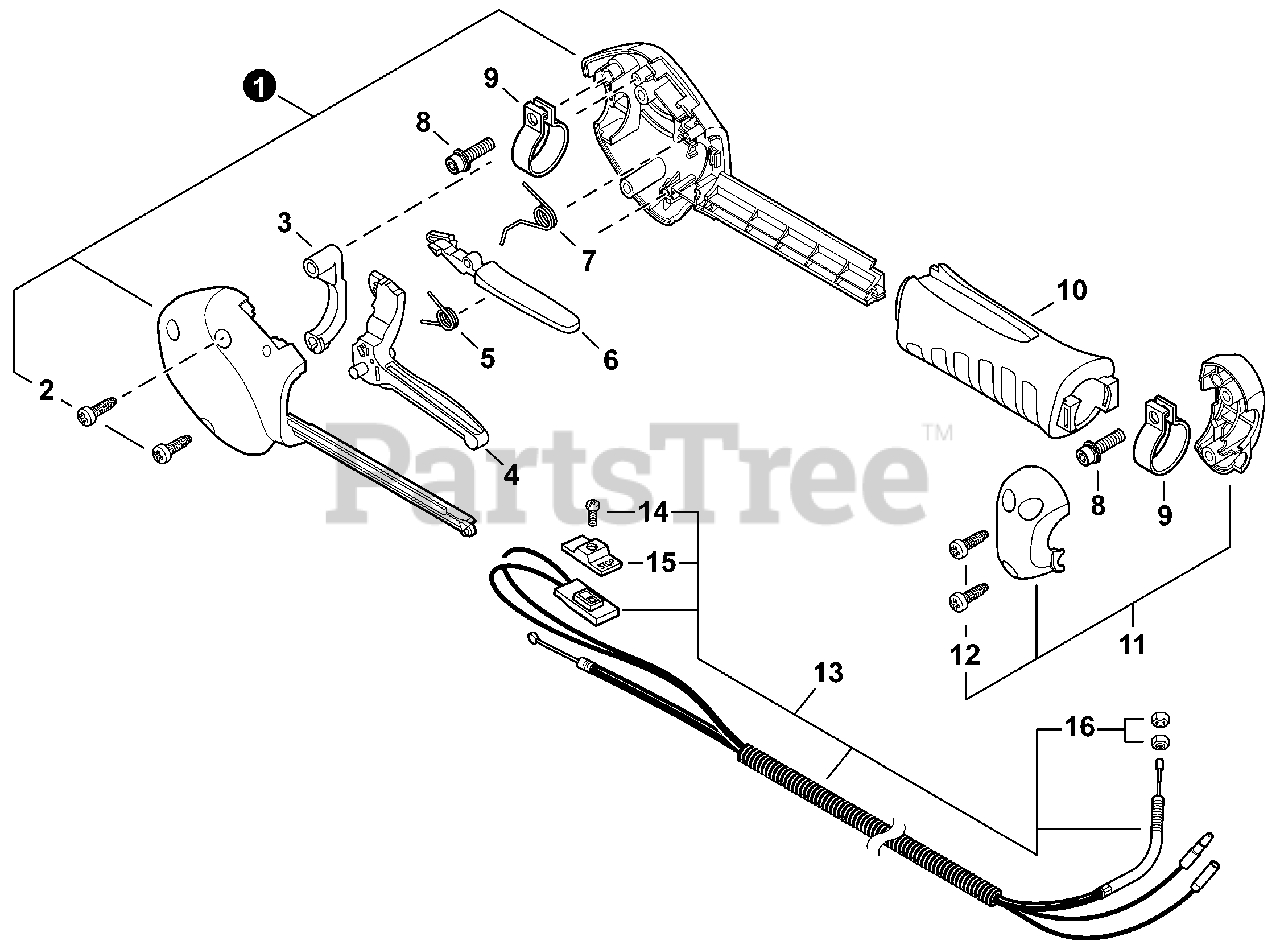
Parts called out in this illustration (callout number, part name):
1	HANDLE KIT, CONTROL
3	LOCKOUT, THROTTLE
4	TRIGGER, THROTTLE
5	SPRING, TORSION
6	LEVER, THROTTLE LOCKOUT
7	SPRING, TORSION
8	BOLT 5×20
10	GRIP, HANDLE
11	FIXTURE SET, HANDLE
13	CABLE ASSY, CONTROL
14	SCREW 3×10
15	KNOB, SWITCH - ORANGE
